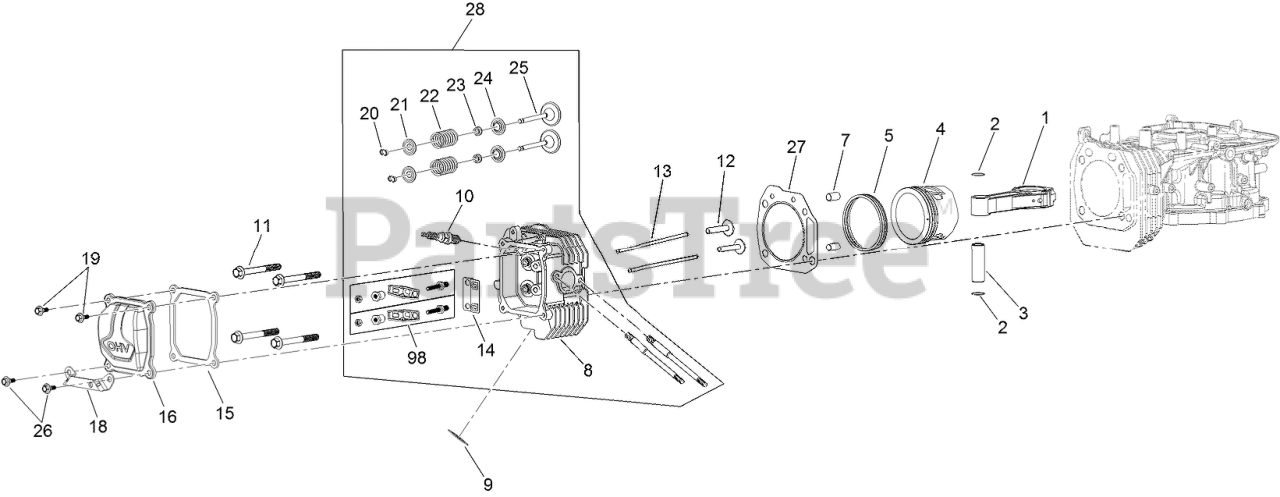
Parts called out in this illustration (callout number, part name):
1	CONNECTING ROD ASM
2	RING-RETAINING, PISTON PIN
3	PIN-PISTON
4	PISTON
5	RING SET
7	PIN-DOWEL
8	HEAD-CYLINDER
9	GASKET-EXHAUST
10	PLUG-SPARK
11	SCREW-HHF
12	LIFTER-VALVE
13	ROD-PUSH
14	PLATE-GUIDE, PUSH ROD
15	GASKET-COVER, VALVE
16	COVER-VALVE
18	BRACKET-MUFFLER
19	SCREW-SHOULDER, HHF
20	KEEPER-VALVE
21	RETAINER-SPRING, VALVE
22	SPRING-VALVE
23	SEAL-STEM, VALVE
24	SEAT-SPRING, VALVE
25	VALVE SET
26	SCREW-SHOULDER, HHF
27	GASKET-CYCLINDER
28	COMPLETE HEAD ASM
98	ROCKER ARM KIT
